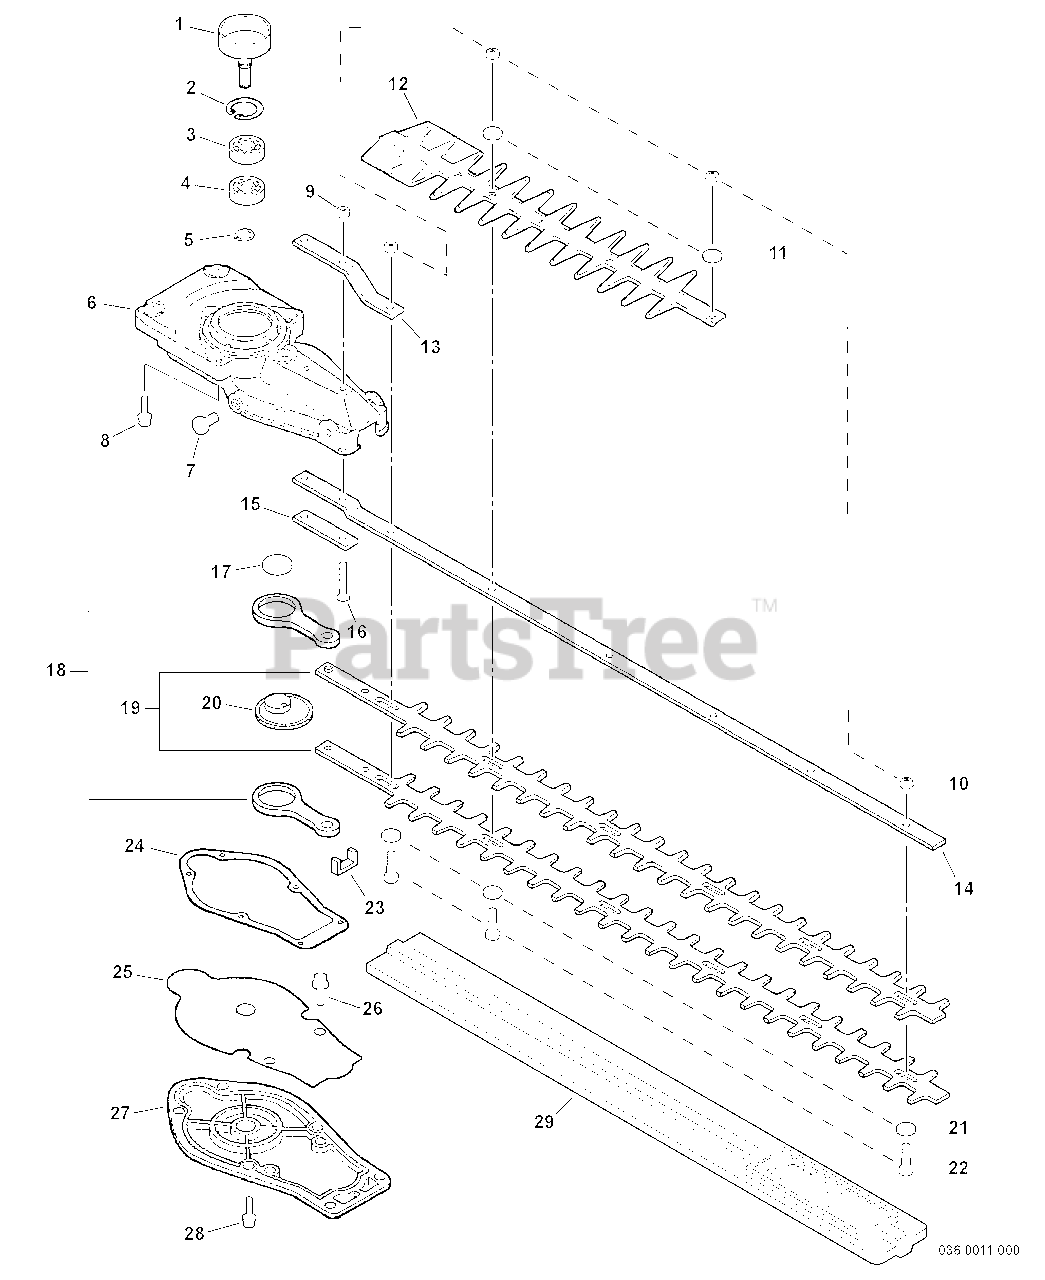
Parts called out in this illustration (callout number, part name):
1	DRUM, CLUTCH
2	RING, RETAINING - 35
3	BEARING, BALL - 6202
4	BEARING, BALL - 6202
5	RING, RETAINING - 14
6	CASE, GEAR - UPPER
7	BOLT - 8X8
8	SCREW - 5X25
9	LOCKNUT - 6
10	LOCKNUT - 6
11	WASHER - 6
12	SUPPORT, BLADE
13	PLATE, ANGLE
14	SUPPORT, BLADE
16	SCREW - 6X25
18	ROD, CONNECTING
19	BLADE, TRIMMER
20	GEAR - DRIVE
21	WASHER - 6
23	SEAL, FELT
24	GASKET, GEAR CASE
25	LID, GEAR CASE
26	SCREW - 5X12
27	LID, GEAR CASE - LOWER
28	SCREW - 4X12
29	COVER, BLADE
